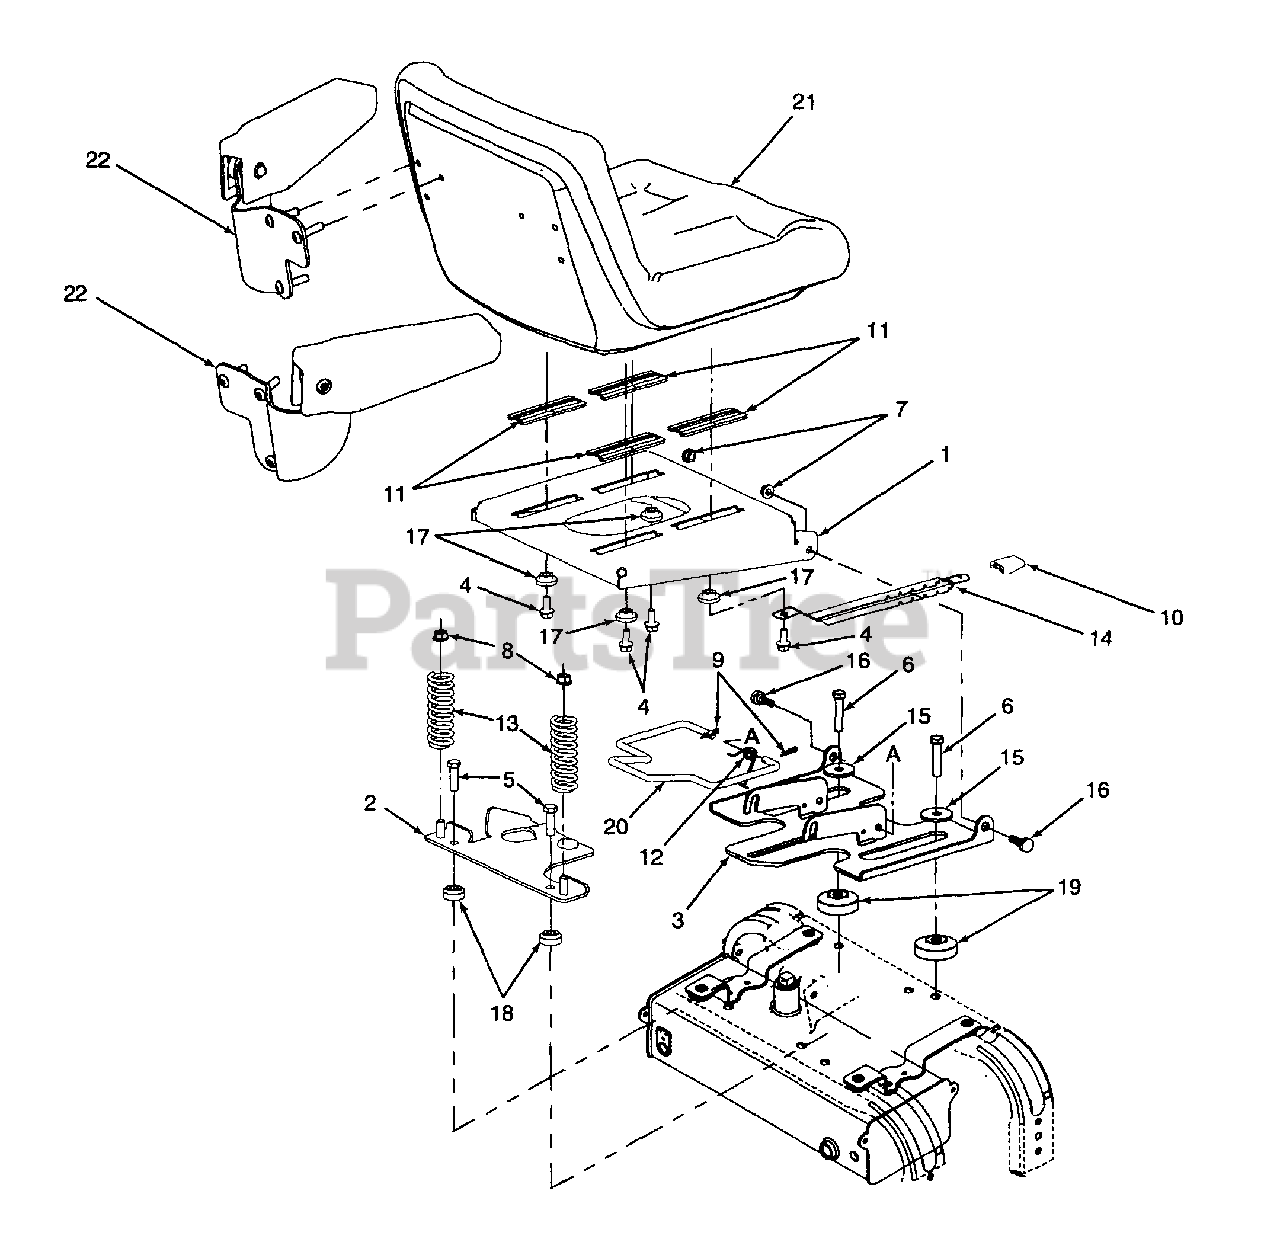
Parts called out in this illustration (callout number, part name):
4	Screw, Hex Wash Hd Tapp 5/16-18 x .75
5	Screw, Hex Cap 3/8-16 x 1.5 GR5
6	Screw, Hex Cap, 3/8-16 x 1-3/4 GR5
7	Nut, Hex Flange Lock 5/16-18 GR5
8	Nut, Hex Flange Lock 3/8-16 GR5
9	Pin, Internal Cotter
10	Knob, Seat Adjustment
12	Spring, Torsion
13	Spring, Compression
14	Spring, Index
15	Washer, Flat, .390 x 1.5 x .134
16	Bolt, Shoulder .437 x .268: 5/16-18
17	Spacer, Shoulder, .38 I.D
18	Spacer, Shoulder
19	Spacer, Seat Pan Shoulder
20	Rod, Seat Pan Lock
21	Seat Assembly
22	Seat Arm (Set of Two)
